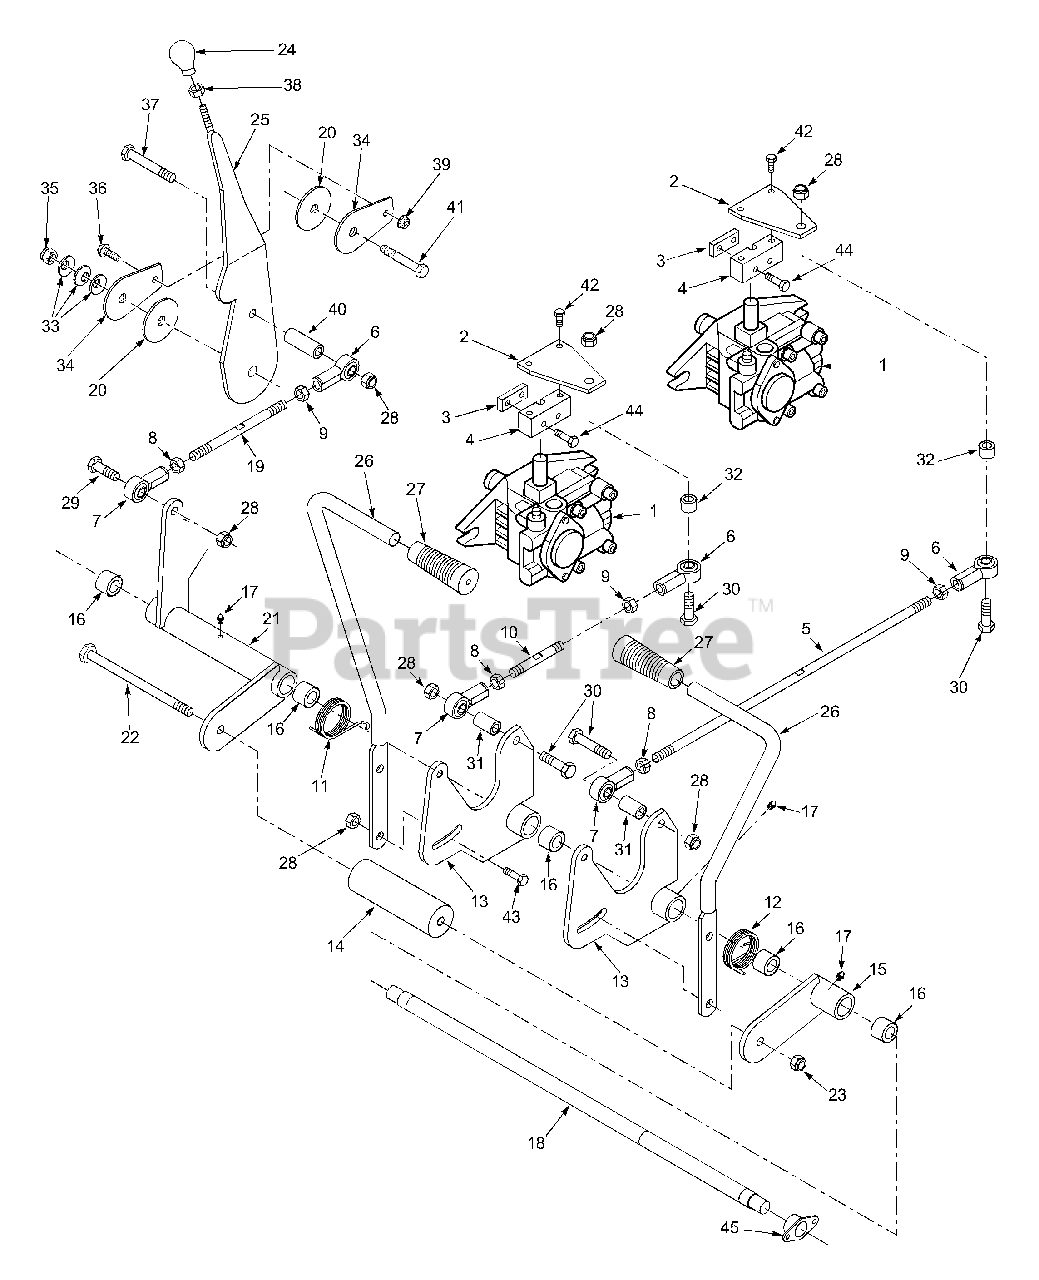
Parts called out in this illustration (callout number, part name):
1	Pump, Hydraulic
2	Lever, Pump
3	Clamp, Pump Control
4	Block, Pump Control
5	Rod, Threaded 3/8-24 x 14.675"
6	Rod End, 3/8-24 RH Thread Female
7	Rod End, 3/8-24 LH Thread Female
8	Nut, Jam 3/8-24 LH Thread
9	Nut, Jam 3/8-24 RH Thread
10	Rod, Threaded 3/8-24 x 2.925"
11	Spring, Torsion RH
12	Spring, Torsion LH
13	Weldment, Steering Control
14	Spacer, Lever Stop
15	Weldment, Speed Control LH
16	Buching, .753 ID Sint.
17	Fitting, Grease 1/4-28
18	Shaft, Steering Lever
19	Rod, Threaded 3/8-24 x 3.75"
20	Disc, Friction
21	Weldment, Speed Control RH
22	Bolt, Hex Head 3/8-16 x 6"
23	Locknut, 3/8-16 Elastic
24	Knob, Speed Control Lever
25	Lever, Speed Control
26	Lever, Steering
27	Grip, Steering Lever
28	Nut, Elastic Stop 3/8-16
29	Bolt, Hex Head 3/8-16 x 1.5"
30	Bolt, Hex Head 3/8-16 x 1.75"
31	Spacer
32	Spacer
33	Washer, Belleville 5/8"
34	Plate, Speed Selector
35	Nut, Elastic Stop 5/8-11
36	Bolt, 5/16-18 x 1.25" Capscrew
37	Bolt, Hex Head 3/8-16 x 2.25"
38	Nut, 3/8-16 Jam
39	Nut, 5/16-18 Serrated Flange
40	Spacer
41	Bolt, Hex Head 5/16-18 x 2.25"
42	Bolt, Hex Head 5/16-18 x .75"
43	Bolt, Hex Head 3/8-16 x 1.25"
44	Bolt, Hex Head 1/4-20 x 1.25"
45	Bushing, Self-Aligning
